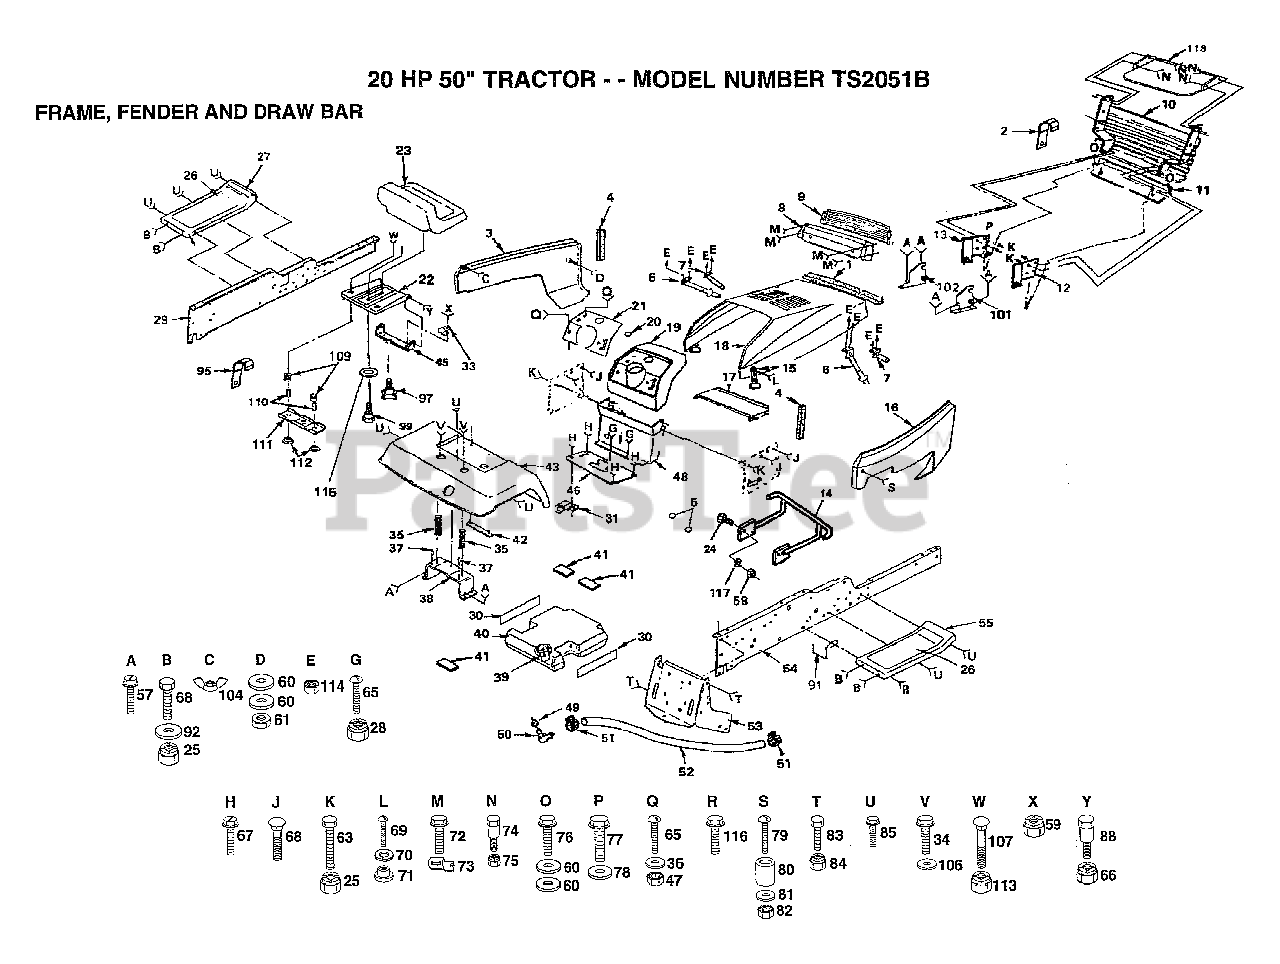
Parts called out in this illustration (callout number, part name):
1	FOAM STRIP T
4	FOAM STRIP T
5	CAP SPRING
9	LENS LT
12	SUPPORT RH YTH
13	SUPPORT LH YTH
14	BUMPER ASSY.
15	HOOD LATCH T
16	PANEL SIDE RH
17	SUPPORT BATRY VGT
19	DASHBOARD BLACK
20	PLUG-DASH T
24	BOLT
25	NUT
26	FOOTREST PAD
28	NUT
30	PAD IDLER TI
31	"CLIP,INSULATOR"
33	CLIP T
34	SCREW LT
35	SPRING COMPRESSIO
36	WASHER
37	NUT-PUSH YT
38	BRKT.ASM.FENDER
41	PAD-SPACER LT
42	STRAP ASM FENDER
43	FENDER
46	SADDLE.6SP.GT
48	DASH ASSEMBLY
49	BUSHING OUTLET T
50	STEM.TANK.FUEL
51	HOSE CLAMP
53	DRAWBAR GT
57	SCREW
60	WASHER PM
63	BOLT
65	SCREW
66	NUT
67	SCREW
68	SCREW LT
69	SCREW
70	LOCKWASHER
71	WELDNUT
73	"""J"" FASTENER LT"
75	NUT
76	SCREW
77	SCREW
78	WASHER
79	SCREW
80	SPACER LT
81	WASHER
83	BOLT
84	NUT.7/16
85	SCREW LT
88	BOLT.SHLD.5/16-18
91	BELT RETAINER GT
92	WASHER
97	"KNOB 1/2"" YT"
99	"BOLT,SHOULDER"
101	SUPPORT RH YTH
102	SUPPORT LH YTH
106	WASHER
109	SPRING COMPRESSED
110	SPACER SPLIT
111	BRKT SWITCH
112	BUSHING
114	NUT
115	WASHER
116	SCREW GTV
117	WASHER
118	"SHIELD,HEAT"
